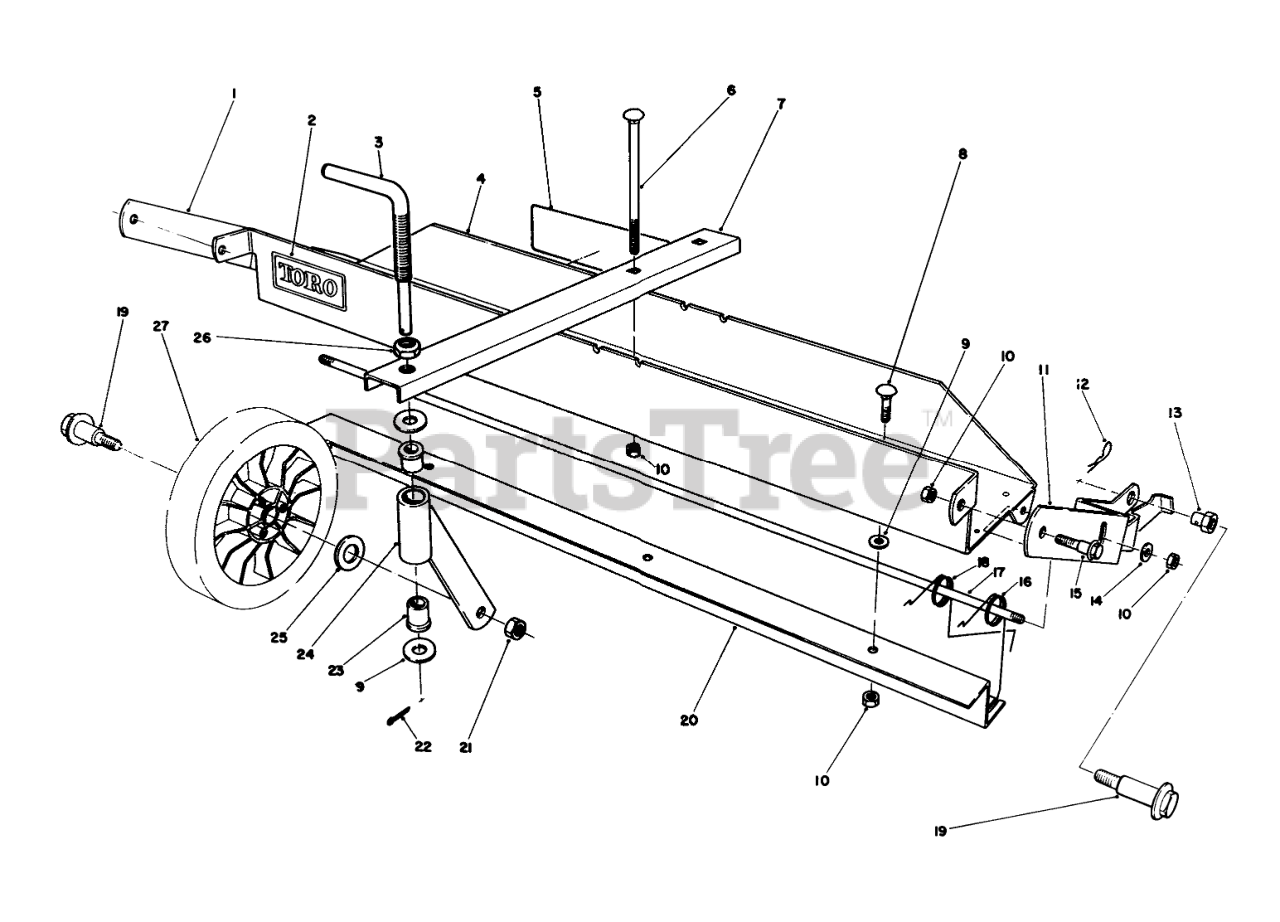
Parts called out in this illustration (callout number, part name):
1	Frame R.H.
2	Decal-Toro
3	CASTOR ADJ ROD
4	Frame-Main (Incl. Ref. #2)
5	Decal-Instruction
6	SCREW-CARR
7	Castor Frame
8	BOLT-CARR
9	WASHER-PLAIN
10	NUT-HEX, SIDE DEFORM
11	LH MTG FRAME
12	PIN-COTTER, HAIR
13	PIVOT NUT
14	WASHER-FLAT
15	BOLT-SHOULDER
16	DETHATCHER SPRING
17	SPRING SUPPORT ROD
18	DETHATCHER SPRING
19	BOLT-WHEEL
20	SPRING GUIDE STRAP
21	NUT-LOCK
22	PIN-COTTER
23	FLANGE BUSHING
24	Castor Tube & Support
25	WASHER
26	NUT-JAM
27	Wheel Assembly
